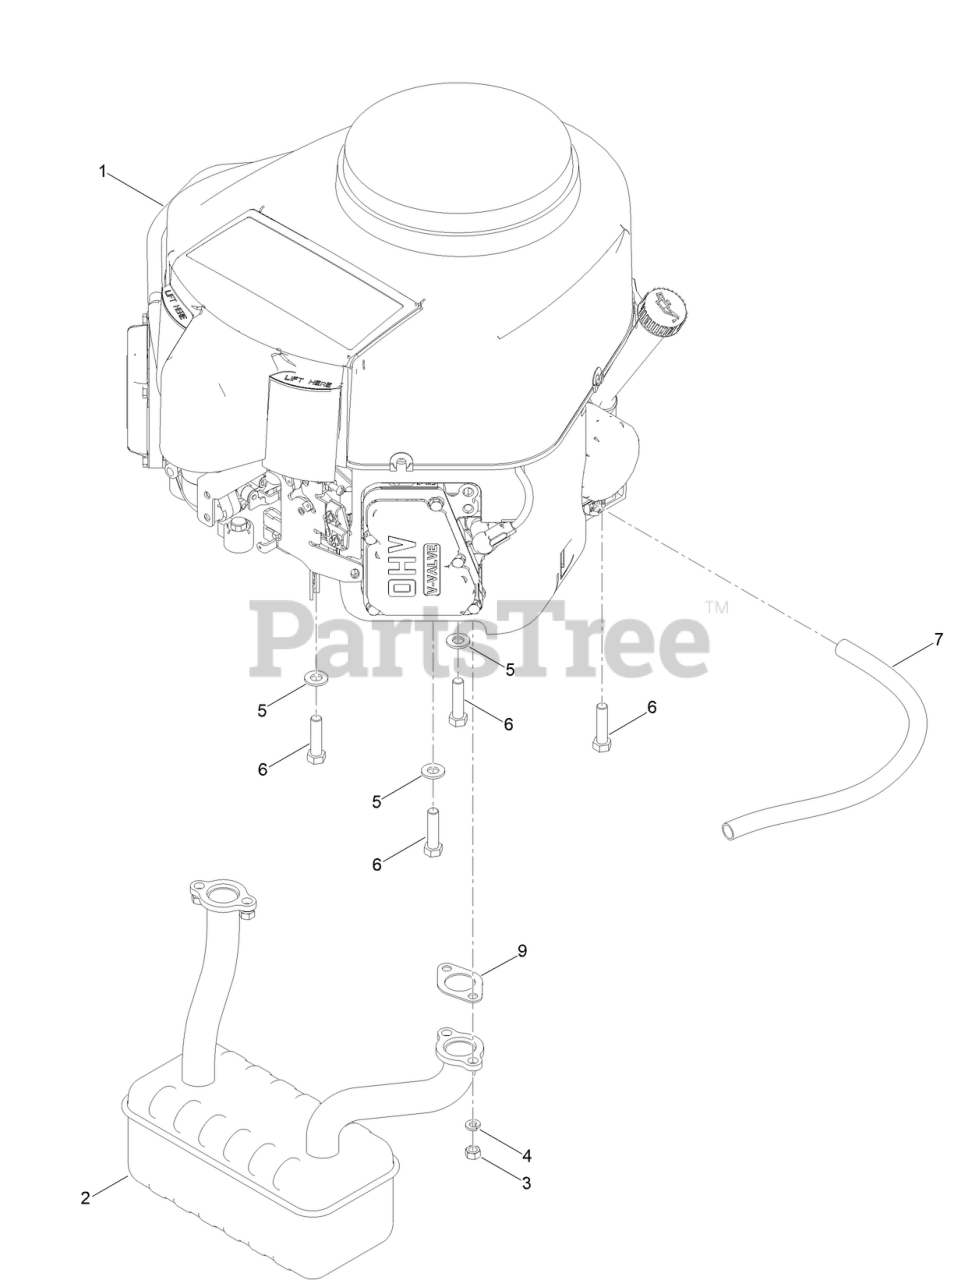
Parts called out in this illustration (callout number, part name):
2	MUFFLER
4	WASHER-LOCK
5	WASHER-FLAT
6	BOLT-HH
7	TUBE-DRAIN, OIL
9	GASKET-EXHAUST
